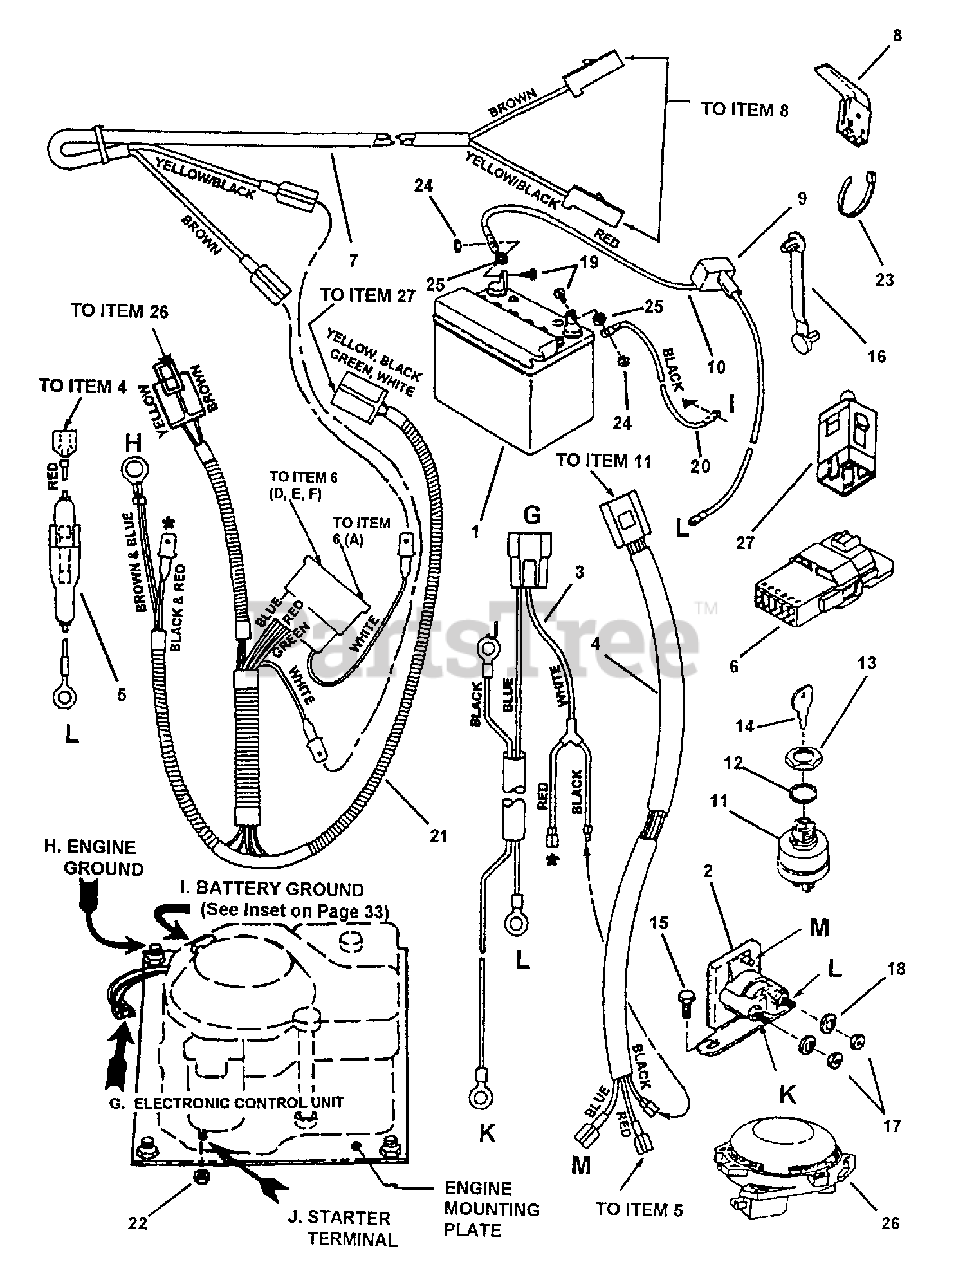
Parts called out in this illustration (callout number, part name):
1	KIT, Battery, 12V, U-1-7RS, 220CCA Dry Charge Snapper No Spill
2	SOLENOID
3	HARNESS, Starter Wiring (Kohler)
4	HARNESS, Ignition Wiring (Kohler)
5	HOLDER, Fuse
6	INTERLOCK Module (Briggs & Kohler)
7	HARNESS, (Deck Interlock Wiring)
8	SWITCH, Deck Interlock (NO)
9	COVER, Battery Cable
10	CABLE, Positive (Red) (17" Long)
11	SWITCH, Ignition
12	WASHER, 5/8 Internal Tooth Lock
13	NUT, 5/8-32 Hex
14	KEY, Switch (2)
15	SCREW, 1/4-20 x 1/2" Hex Washer Self-Tap
16	TIE, 2" Long Cable
17	NUT, 1 /4-20 Hex
18	WASHER, 1/4 Internal Tooth Lock
19	SCREW, 1/4-20 x 5/8" Hex Head Cap, Grade 5
20	CABLE, Negative (15" Long)
21	HARNESS, Operator Presence Control Wire
22	NUT, 1/4-20 Hex, Grade 5 or B
23	TIE, 7" Long Cable
24	NUT, 1/4-20 Hex Center Lock
25	RETAINER, 1/4 Bolt
26	SWITCH, Seat (NC)
27	SWITCH, Operator Presence Control (OPC) Traction (NC/NO)
